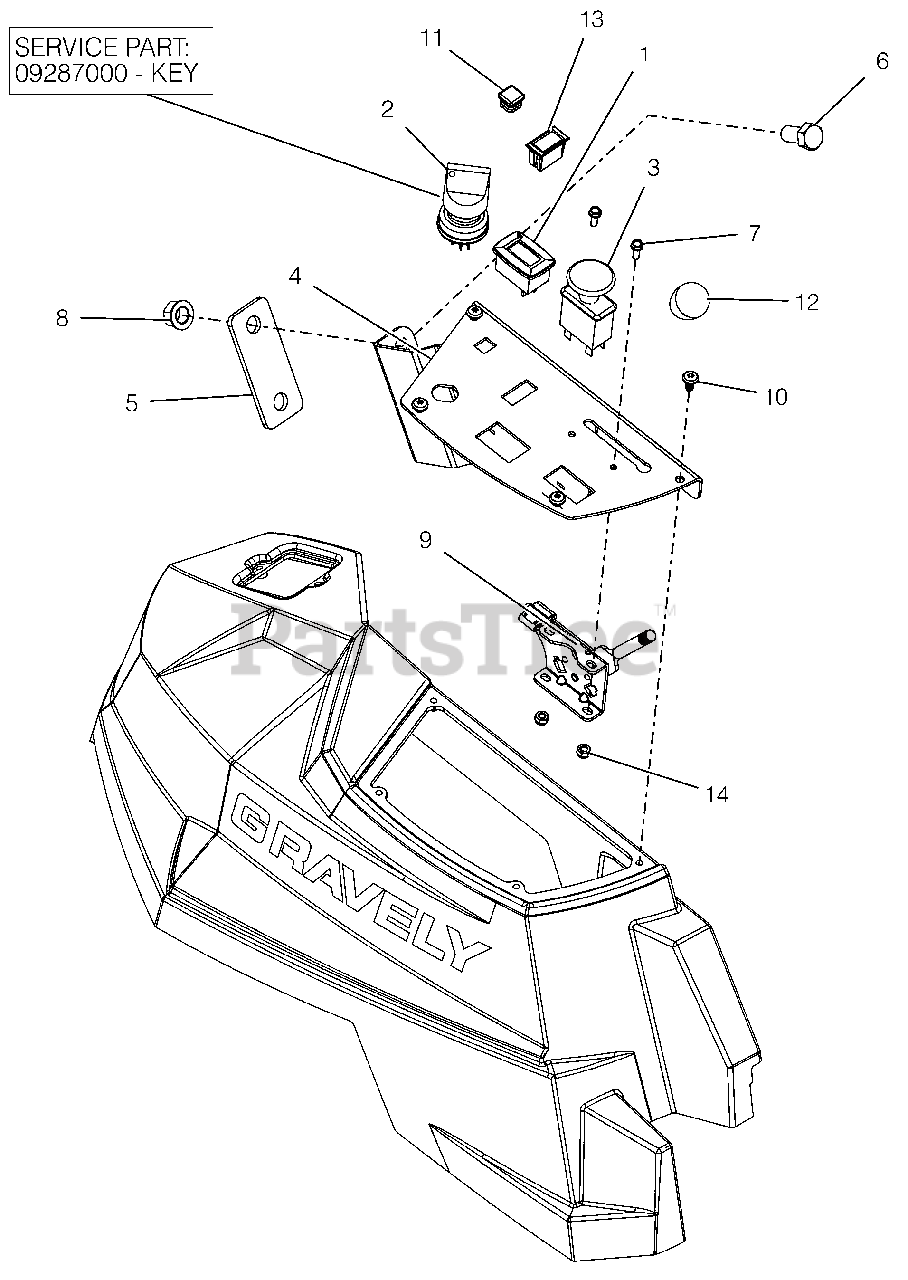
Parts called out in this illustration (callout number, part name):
1	METER, HOUR W/MAINTENANCE
2	SWITCH, IGNITION
2	KEY, W/ SHIELD
3	SWITCH, CLUTCH
4	PANEL, HD CONTROL
5	PLATE, CONTROL PANEL SPACER
6	@BLT-HEX .50-13X1.00 GR5 YWZC
7	@SCR-MCH 10-24X.50 HWH YWZC
8	@NUT-LK-TOP-FLG .50-13 YWZC
9	CABLE, PRO THROTTLE CONTROL
10	SCR-PAN .25-15X.50 6L H/LZB500
11	PLUG, 5/8" SQ BLACK (14-20GA)
12	KNOB-CONTROL-BLACK .38-16X.50
13	SWITCH,BLANK
14	@NUT-LK-NYL 10-24 W/INSRT YWZC
